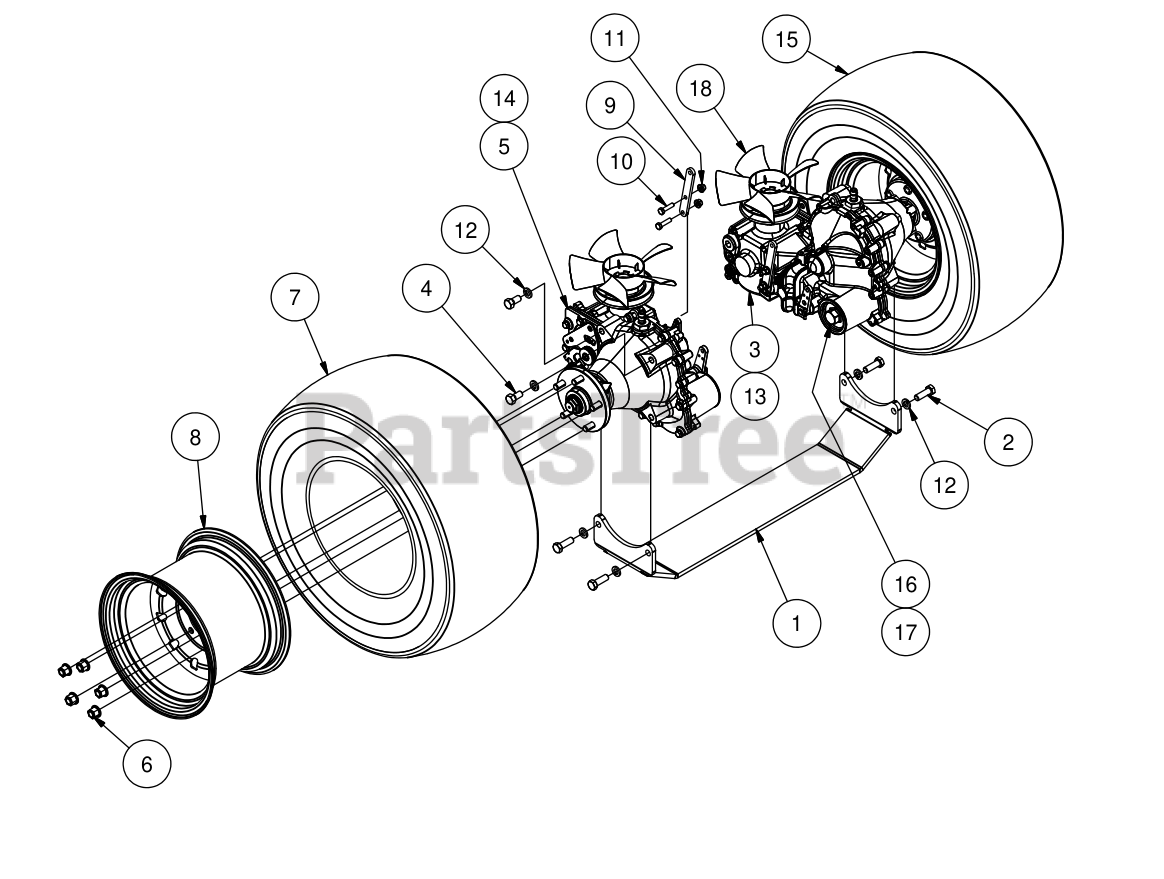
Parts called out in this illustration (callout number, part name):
1	Outlaw Transaxle Cross Brace
2	1/2" x 1 1/2" Hex Bolt
3	ZT-5400 - Left (Extreme Only)
4	1/2" x 1" Hex Bolt
5	ZT-5400 - Right (Extreme Only)
6	Acorn Lug Nut
7	24 x 12 - 12 Tire Pro Maxxis
8	12x12" Black Wheel For 2015 Outlaw
9	2015 Outlaw Brake Adapter (4400 Transaxles Only)
10	5/16 x 1 1/4 Hex Bolt (4400 Transaxles Only)
11	5/16" Flange Nut Zinc W/Serrations (4400 Transaxles Only)
12	1/2" Lock Washer
13	4400 Transaxle - Left (Base Outlaw)
14	4400 Transaxle - Right (Base Outlaw)
15	24 x 12 - 12 Tire and Black Wheel Assembly
16	Hydro Filter for Outlaw Extreme
17	4400 Hydro Filter for Outlaw
18	Fan/Pulley Kit for Outlaw
